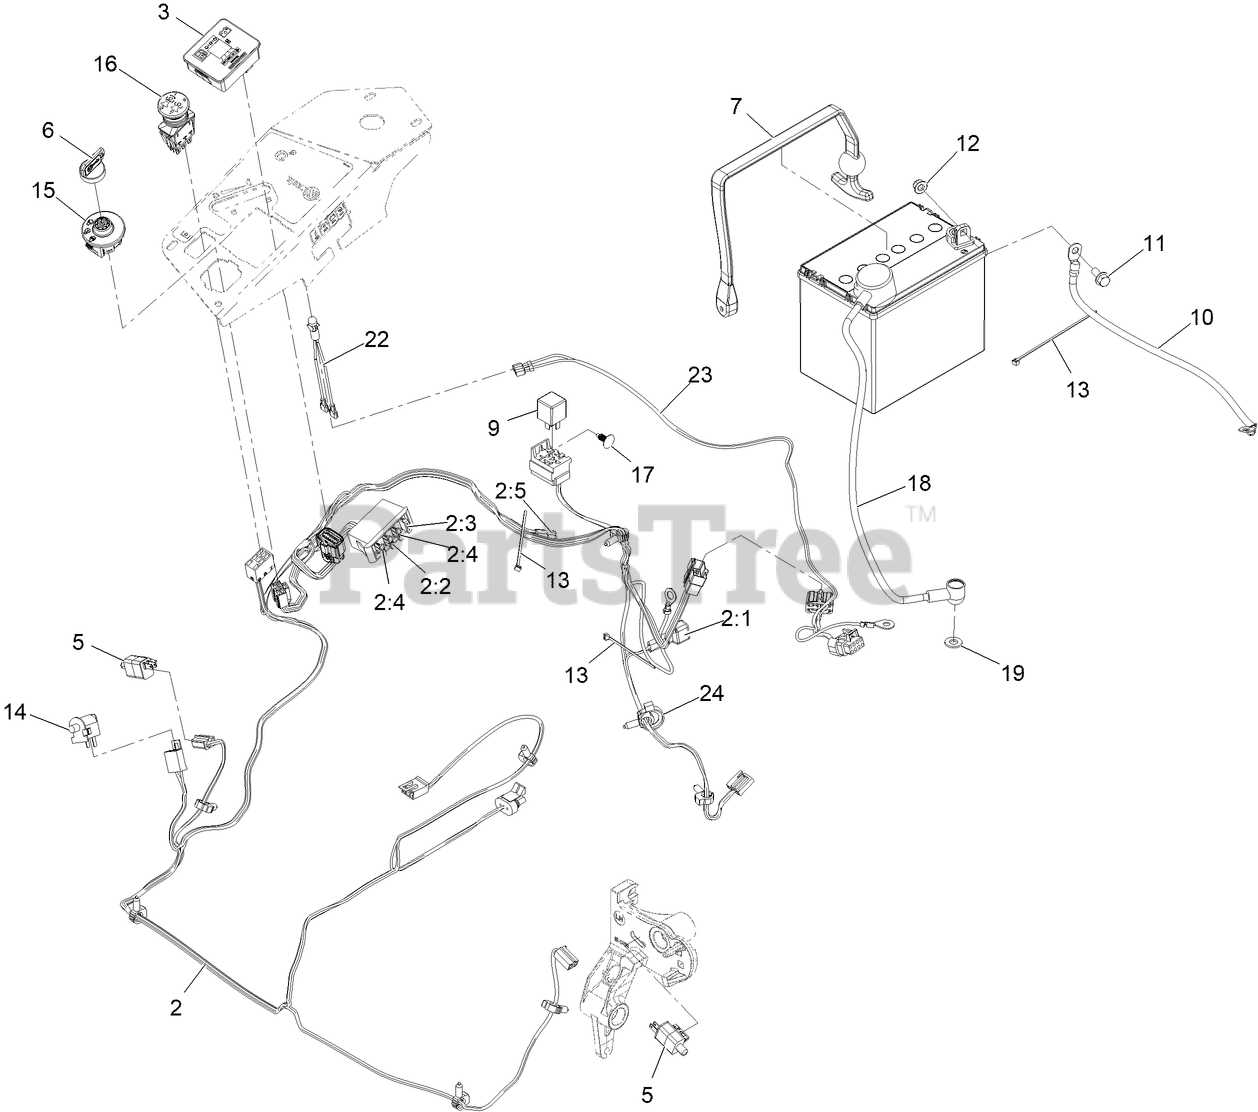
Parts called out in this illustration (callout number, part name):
2	HARNESS-WIRE, MAIN
2:2	FUSE-BLADE, 10 AMP
2:3	FUSE-BLADE, 15 AMP
2:4	FUSE-BLADE, 25 AMP
2:5	CAP-PLUG
3	FUEL/HOUR METER ASM
6	KEYS-IGNITION (SPARE PAIR
6	KEY-IGNITION
7	Strap-Bungee
10	Cable-Battery, Black
11	SCREW-HHF
12	NUT-HF, NI
13	TIE-CABLE
14	SWITCH-BAIL
15	SWITCH-IGNITION
16	SWITCH, PTO 10A
17	PLUG-PLASTIC
18	CABLE-BATTERY, POSITIVE
19	WASHER-PLAIN
22	INDICATOR-LED, RED
23	Harness-Jumper EFI
24	CLAMP-HOSE
